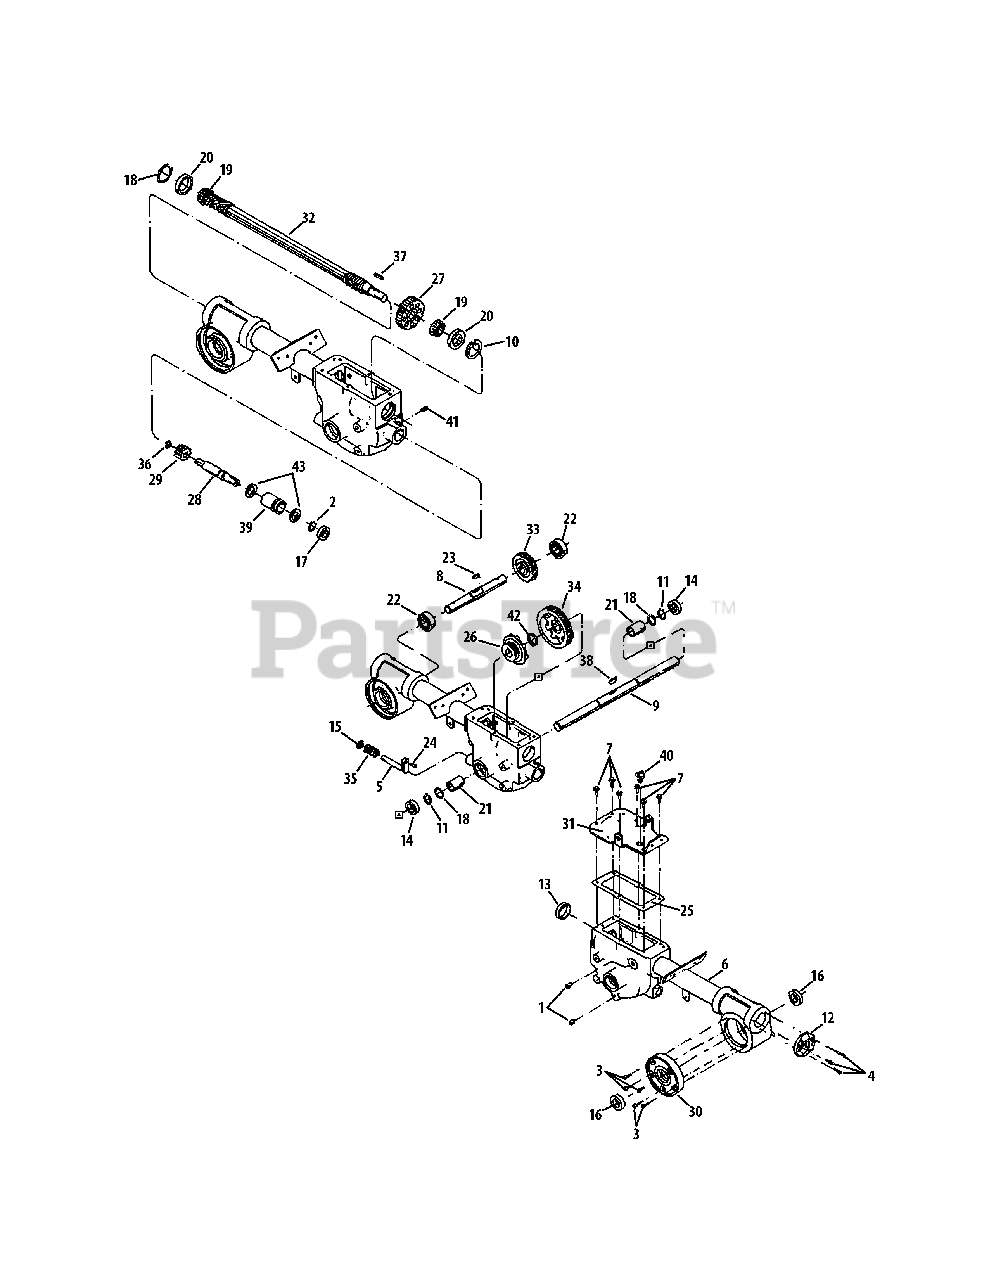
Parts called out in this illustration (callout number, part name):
1	Pipe Plug
2	Retaining Ring
3	Hex Screw, 1/4-20 x .625
4	Self-Sealing Screw, 1/4-20 x .875
5	Eccentric Shaft
6	Transmission Housing
7	Hex Flange Screw, 5/16-18 x .750
8	Tiller Shaft
9	Wheel Shaft
10	Retaining Ring
11	Retaining Ring
12	Rear Bearing Cover
13	Oil Seal, 1.79 x .25
14	Oil Seal, 1.0 x 1.499
15	Oil Seal, .625 x 1.0
16	Oil Seal, .984 x 1.75
17	Oil Seal, .750 x 125
18	Washer, 1.375 x 1.015 x .01
18	Washer, 1.375 x 1.015 x .015
18	Washer, 1.375 x 1.015 x .03
18	Washer, 1.75 x 1.5 x .062
18	Washer, 1.75 x 1.5 x .005
18	Washer, 1.75 x 1.5 x .03
18	Washer, 1.75 x 1.5 x .01
18	Washer, 1.375 x 1.015 x .062
19	Cone Bearing
20	Cup Bearing
21	Bushing, 1.25 x 1 x .005 x 1.5
22	Ball Bearing
23	Woodruff Key, .25 x 1.12
24	Pin, .375 x .72
25	Transmission Cover Gasket
26	Wheel Drive Clutch
28	Pinion Shaft
29	Pinion Gear
30	Housing Cover
31	Transmission Cover
32	Drive Shaft
33	Worm Gear
34	Wheel Drive Gear
35	Spring, .850 x .875
36	Bowed Ring
37	Key, .188 x 1
38	Hi-Pro Key, .25 x 1.312
39	Bushing, 1.24 x .75 x .18
41	Hex Screw, 5/16-18 x .38
42	Washer, 1.46 x 1.016 x .062
43	Washer, 1.022 x .75 x .059
